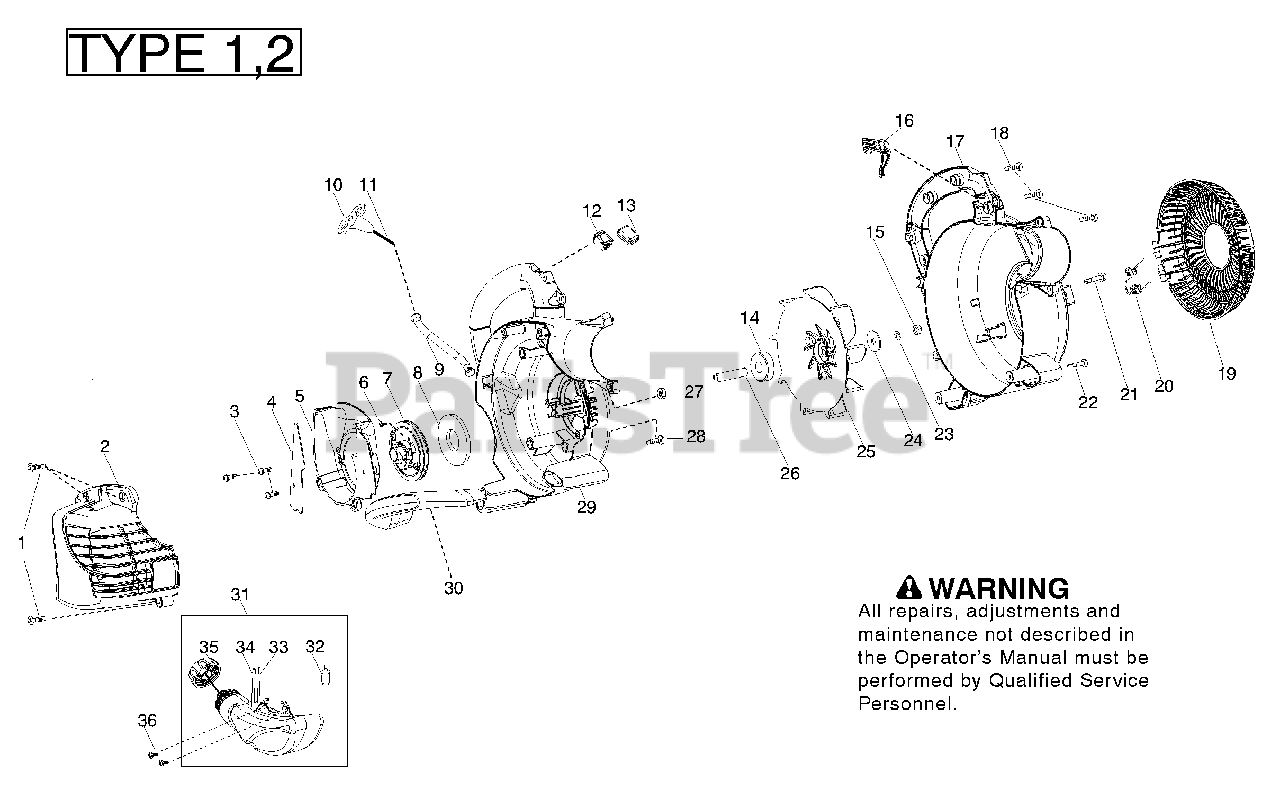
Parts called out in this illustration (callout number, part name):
2	Assy - Engine Cover
4	Shield - Baffle
7	Kit - Starter Pulley
8	Spring -Starter
9	Tube - Starter Rope
10	Handle - starter
11	Kit - Rope
12	Kit - Switch
13	Protector - Switch
16	Trigger - Throttle
17	Assy - Scroll LH
19	Door - Vac
20	Spring - Vac Door
21	Knob - Blower
22	Screw - Vac Handle
23	Washer - Lock
24	Washer - Impeller
25	Assy - Impeller
26	Spacer - Flywheel
27	Nut - Blower Knob
28	Screw
29	Assy - Scroll RH
30	Handle - Vac
31	Assy - Fuel Tank
32	Assy - Fuel Pickup
33	Kit - Fuel Line (carb/purge)
34	Kit - Fuel Line (tank/purge)
35	Assy - Fuel Cap w/retainer
36	Screw - Fuel Tank Retainer
